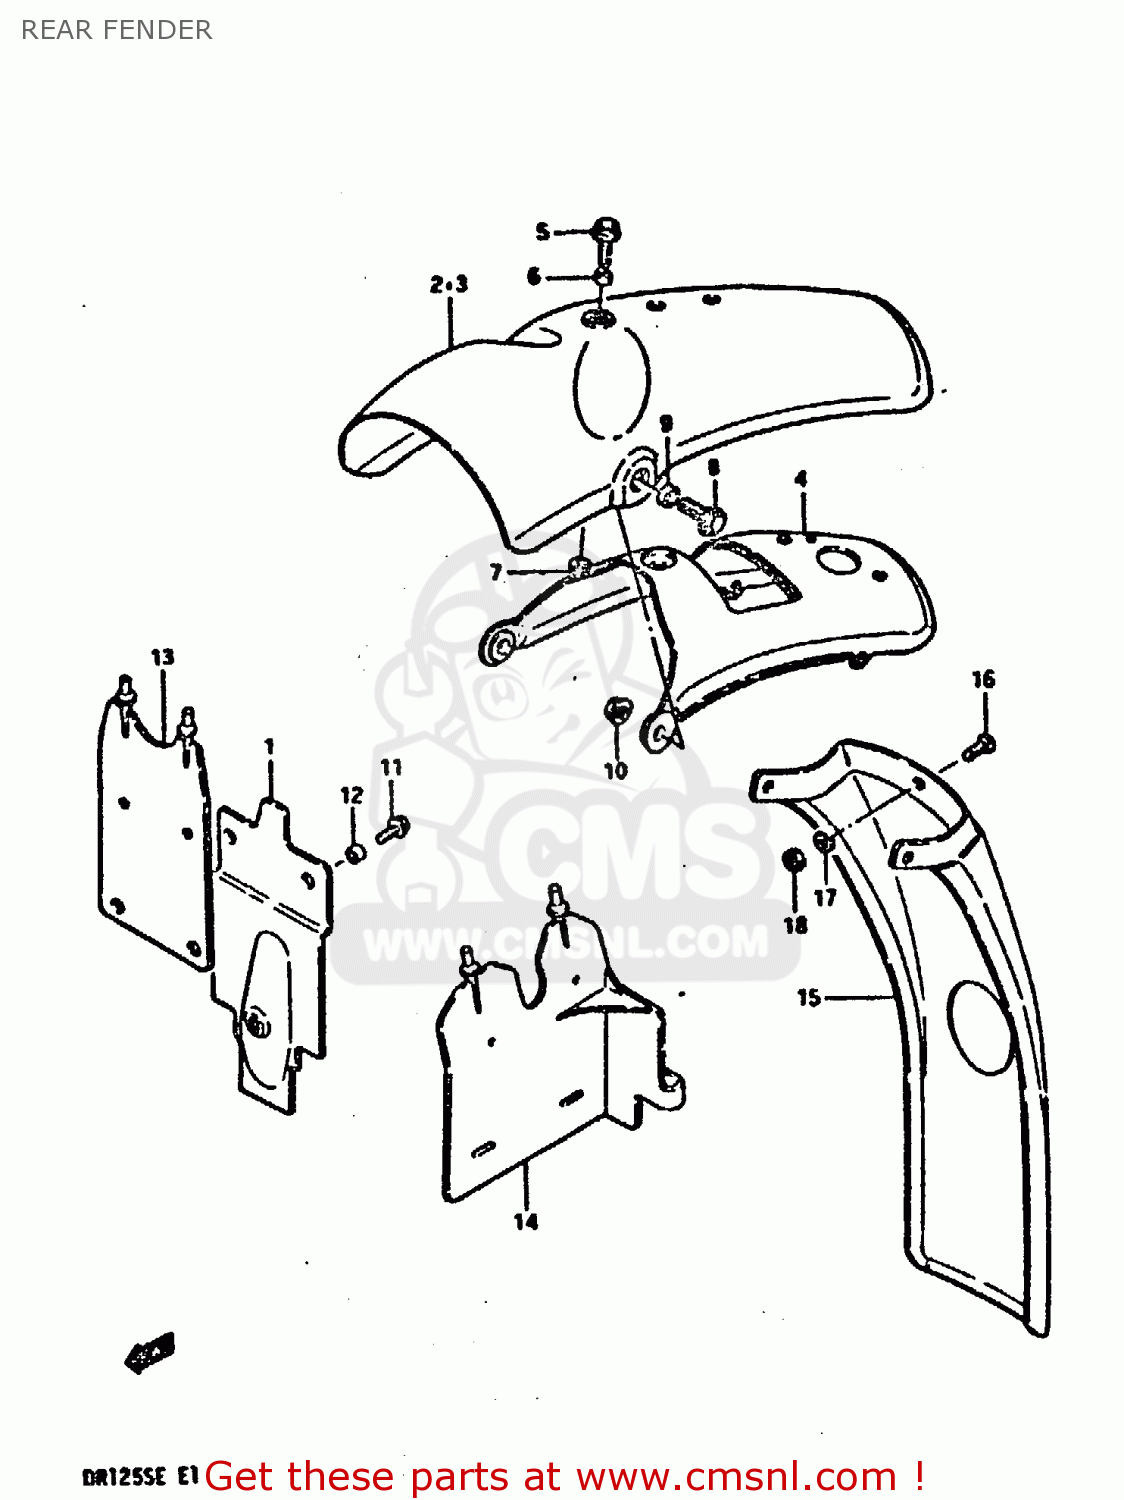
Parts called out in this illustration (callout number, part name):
1	REAR FENDER,FRONT
2	FENDER, REAR (RED)
3	FENDER, REAR (RED)
4	REINFORCEMENT
5	BOLT,REAR
6	SPACER
7	NUT
8	BOLT
9	SPACER
10	NUT
11	SCREW, FRONT
12	SPACER
13	MUD GUARD,REAR FENDER
14	MUD GUARD
15	EXTENSION, REAR FENDER
16	SCREW
17	LOCK WASHER
18	NUT
